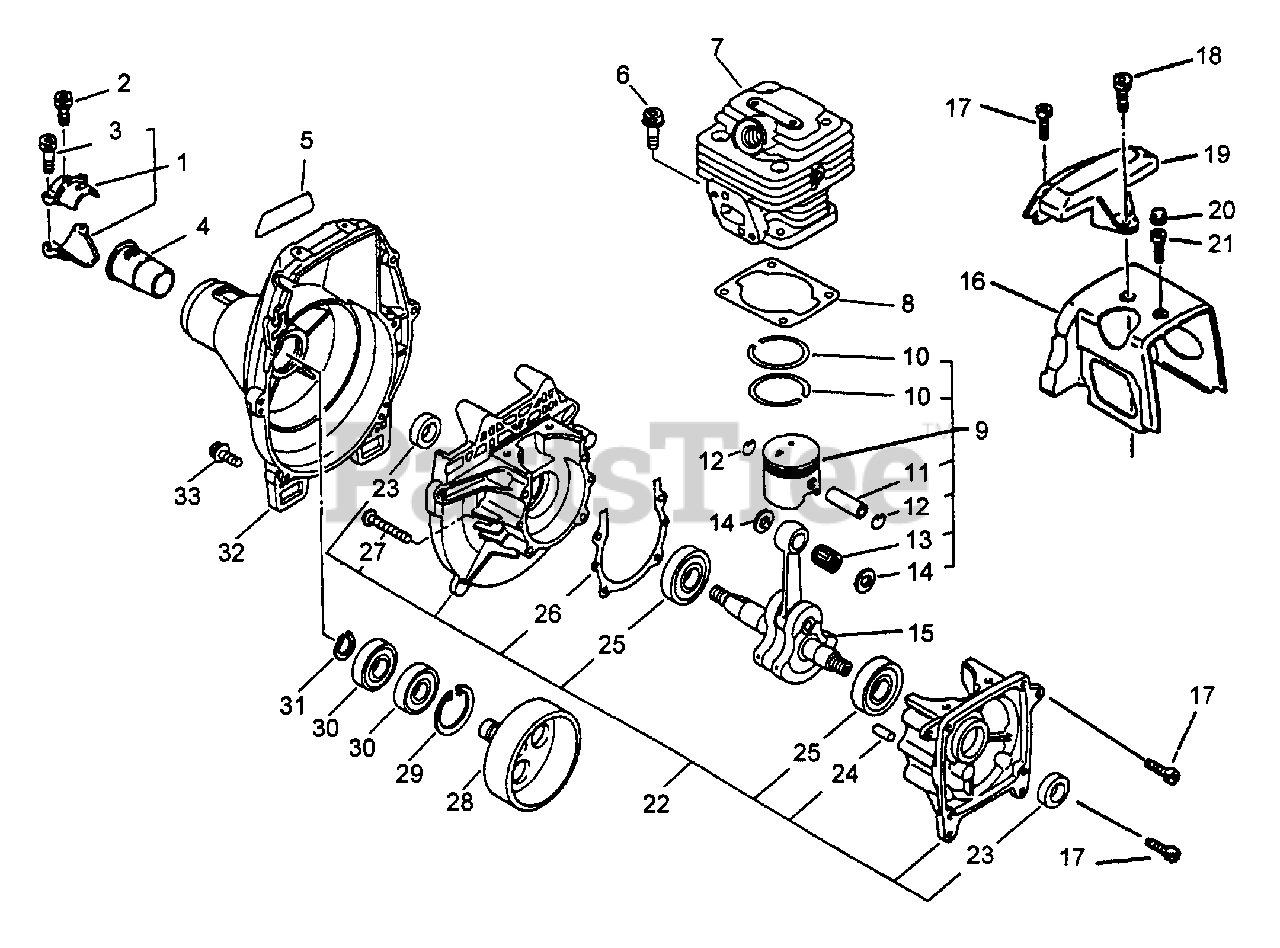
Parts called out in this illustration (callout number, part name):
1	RETAINER KIT
2	BOLT 5×12
3	BOLT 5×25
5	LABEL, ECHO
6	BOLT 5×20
7	CYLINDER
8	GASKET, CYLINDER
9	PISTON KIT
10	RING, PISTON
11	PIN, PISTON
12	RING, RETAINING
13	BEARING, NEEDLE 9
14	WASHER, THRUST
15	CRANKSHAFT ASSY
16	COVER, ENGINE
17	BOLT 4×14
18	BOLT 5×16
19	GUARD, TOP
20	SCREW - SOCKET HEAD CAP
21	BOLT 5×12
22	CRANKCASE KIT
23	SEAL, OIL 12
24	PIN, LOCATING 4
25	BEARING, BALL - 6201 C3
26	GASKET, CRANKCASE
27	BOLT 5×30
28	DRUM, CLUTCH
29	RING, SNAP 28
30	BEARING, BALL 6001
31	RING, RETAINING - 12
32	COVER, FAN
33	BOLT 5×20
